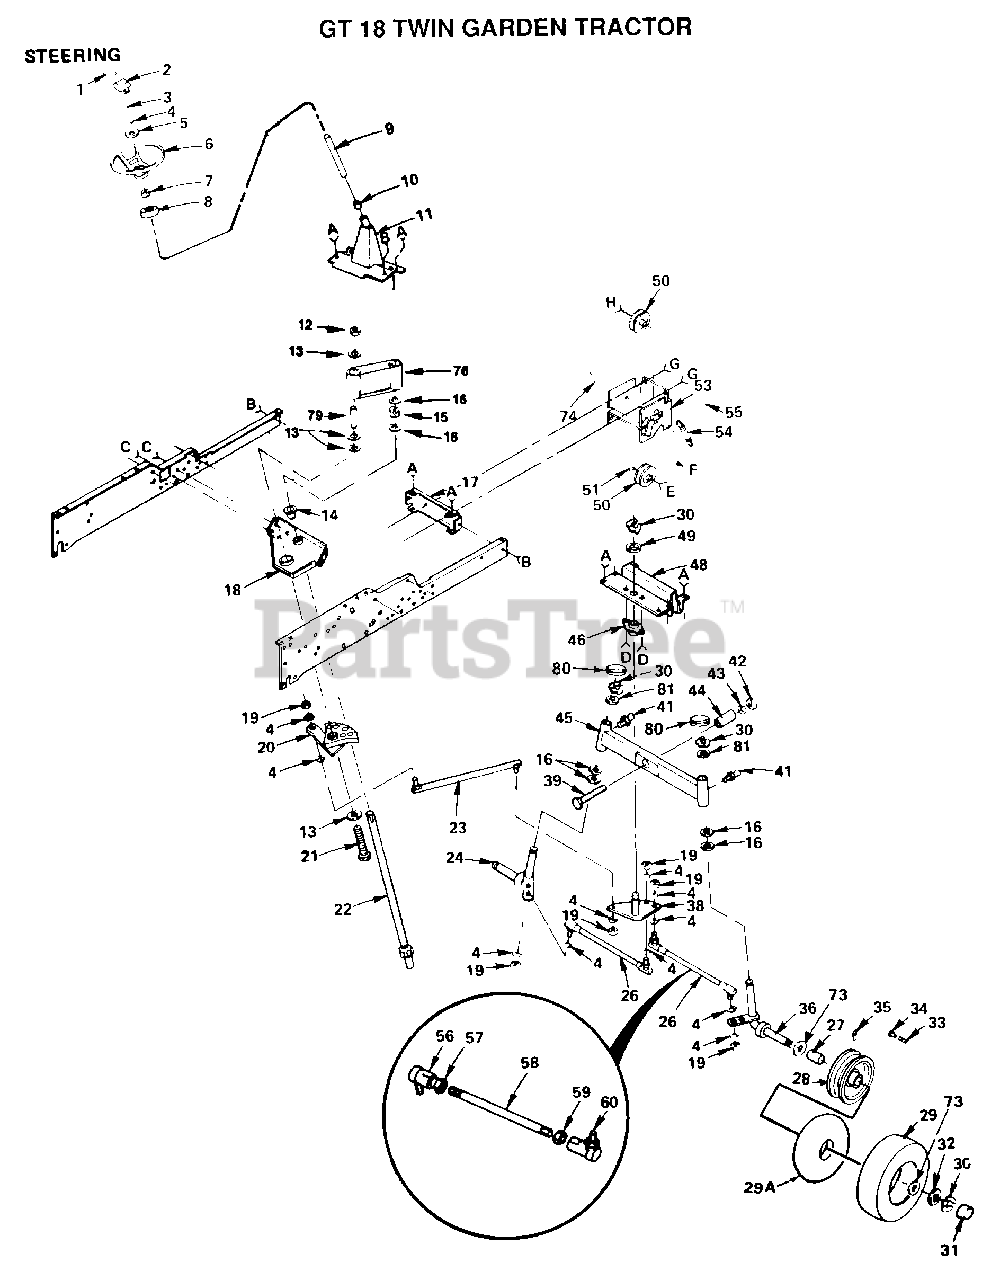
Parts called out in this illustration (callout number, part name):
1	DECAL, STEERING WHEEL INSERT
2	INSERT-WHEEL LT
4	LOCKWASHER
5	WASHER T
7	ADAPTER LT
9	TUBE
10	"T, BEARING"
11	SUPPORT ASSY T
12	NUT LTV
13	WASHER GT
14	"FLANGE GT, BEAR."
15	KLIP RING
16	WASHER .T
17	FRAME BRACKET GT
20	SECTOR T
21	BOLT T
22	SHAFT STEERING GT
23	LINK.DRAG.T
27	"FLANGE, BEARING"
29A	TUBE.16X6.5/7.5-8
30	RING
31	HUB CAP
32	WASHER
33	VALVE CAP
34	VALVE STEM LT
35	FITTING LT
38	"T, BELLCRANK"
39	BOLT
41	ZERK M
42	NUT X
43	WASHER
45	FRONT AXLE T
48	AXLE BRACKET T
49	WASHER
50	IDLER-INSIDE T
51	WASHER T
53	IDLER BRKT T
54	SPRING
57	NUT
58	ROD TIE
59	NUT
73	WASHER
76	COLLAR
79	TUBE T
80	CAP
81	WASHER
